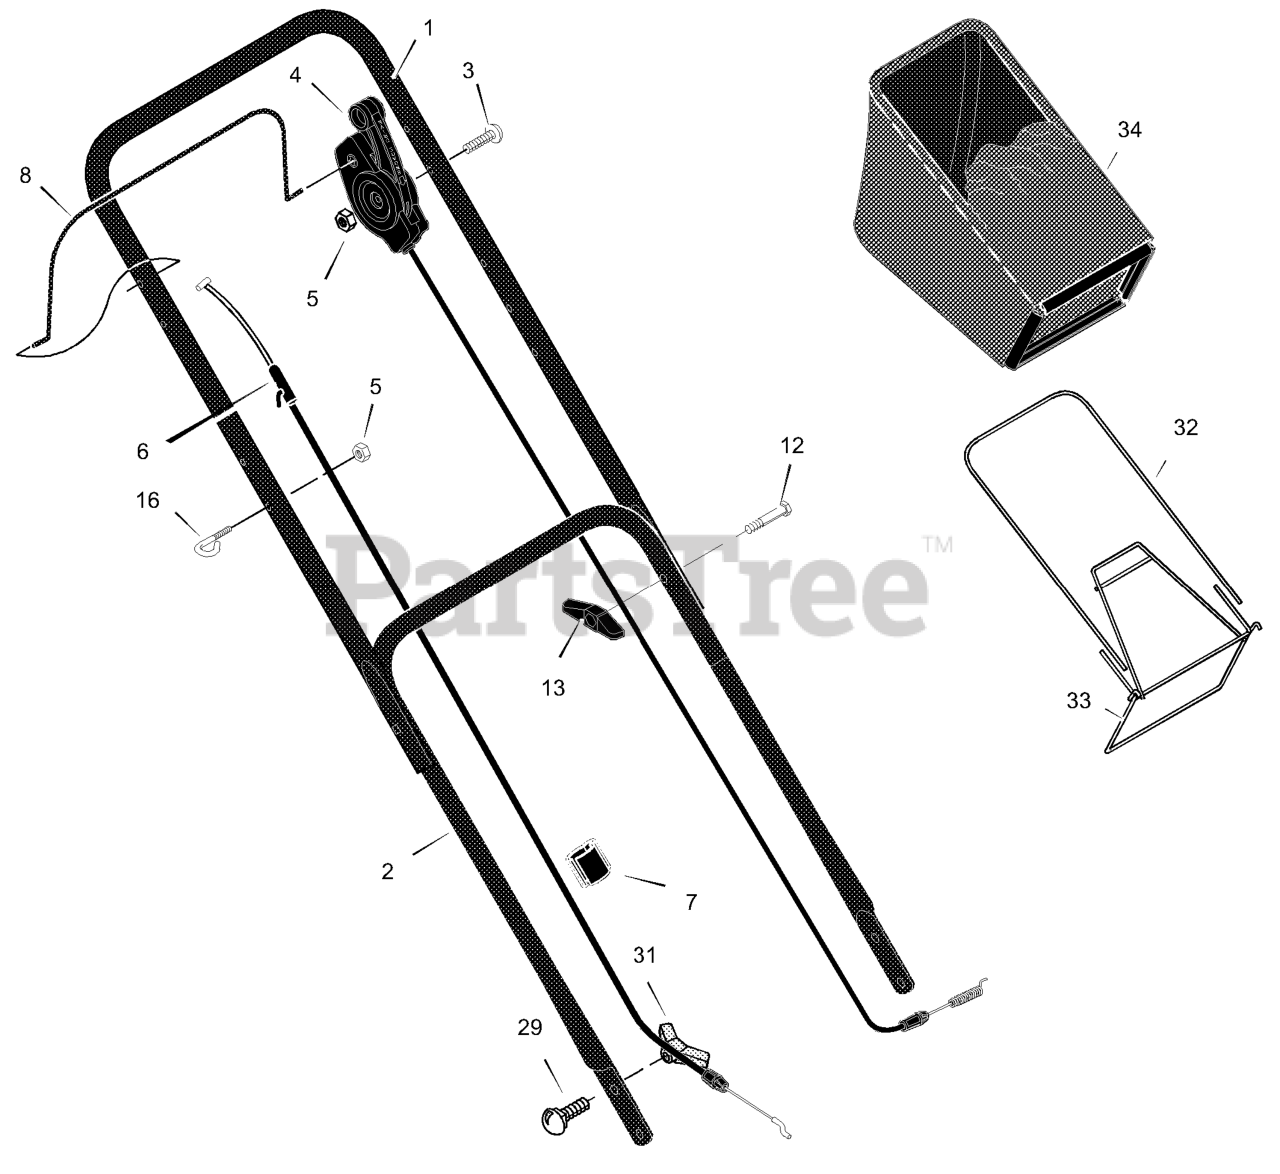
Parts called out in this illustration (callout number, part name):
1	Handle, Upper (Black)
2	Handle, Lower (Black)
4	Control, Drive
5	Locknut
6	Cable, Stop (Briggs)
7	Fastener, Double Cable
8	Lever, Stop
13	Knob
16	Guide, Rope
29	Bolt, Carriage
31	Knob, Plastic
32	Tube, Bag
33	Frame Assembly
34	Bag, Cloth
